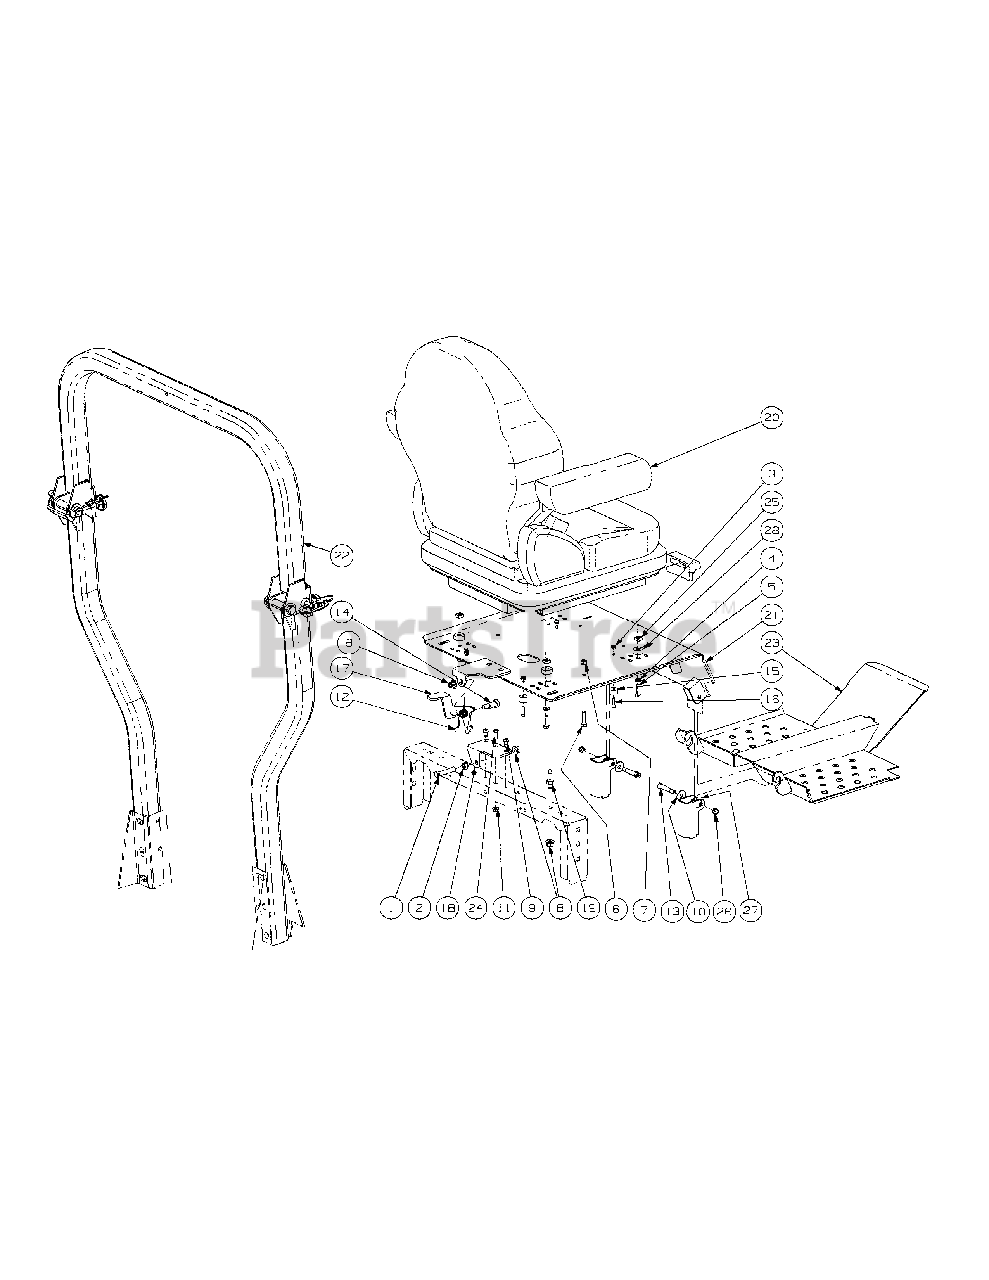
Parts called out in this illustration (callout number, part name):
1	Hex Cap Screw 3/8-16 x 2.00
2	Hex Nut, 3/8-16
3	Nut, 10-24, Nylon Insert
4	Lock Washer, 5/16
5	Hex Cap Screw, 5/16-18 x 1.00
6	Hex Cap Screw, 5/16-18 x 1-1/4
7	Nut, 5/16-18, Center Lock
8	Flange Lock, Hex Nut, 3/8-16
9	Screw, TT, 1/4-20, 0.5, Hex Index Washer
10	Flat Washer, .406 ID, 1.0 OD, .105
11	Lock Nut, 1/4-20
12	Deck Lift Spring, Left Hand
13	Shoulder Bolt, .375 x 1.50
14	Shoulder Bolt, 1/2 x 3/4, 3/8-16
15	Rubber Stop with Washer
16	Standard Cap Screw, #10-24 x .75
17	Latch Lever Bracket
18	Latch Bracket
19	Adjustable Stud
20	Seat w/ Seat Belt & Suspension
21	Seat Plate Assembly
22	Foldable Rops Assembly includes:
23	Floor Panel Assembly
24	Screw, Hex, Cap, 1/4-20 x .75
25	Nut, 5/16-18
26	Nut, 5/16-18, Nylock
27	Grommet, .38 ID x .75 OD x .75
28	Spacer, .406 ID x 1.00 OD x .38
